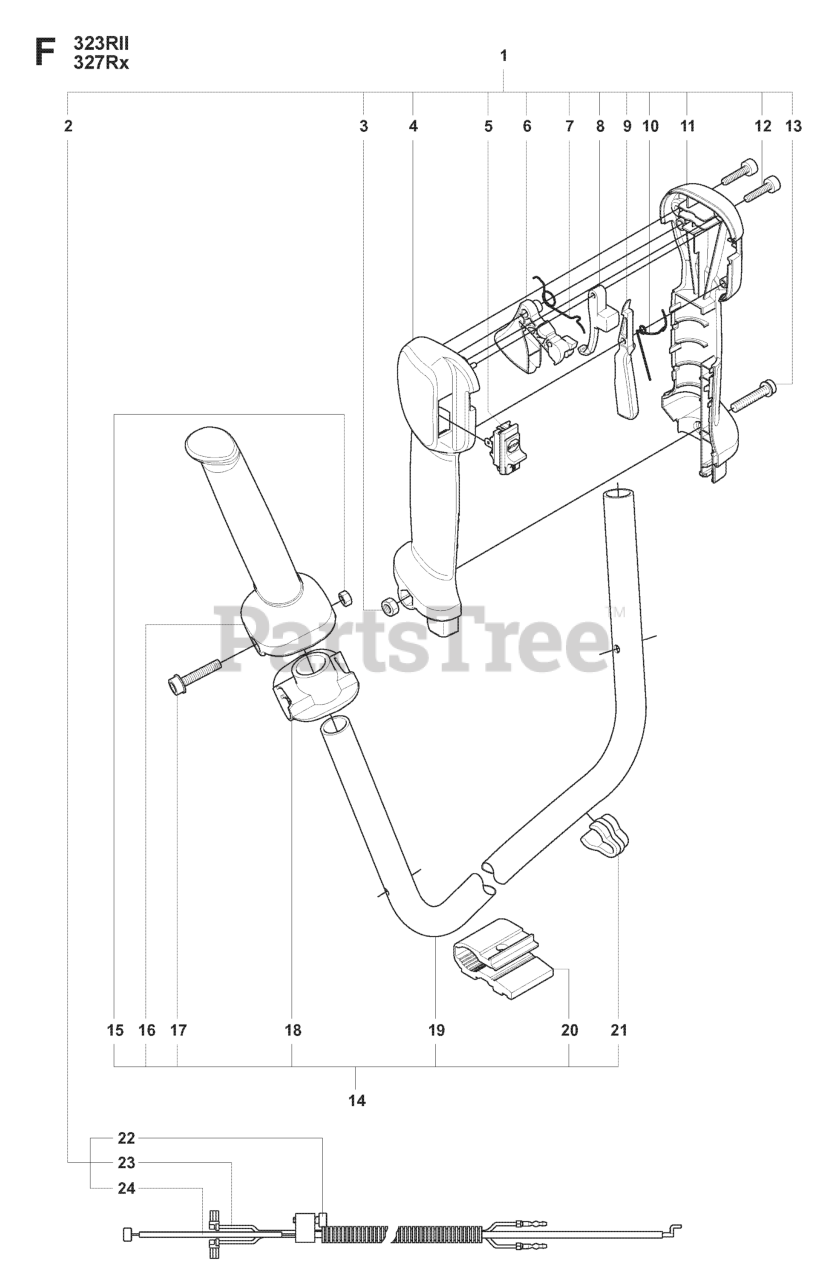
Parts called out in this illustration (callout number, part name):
1	HANDLE SYSTEM ASSY
4	HANDLE
5	STOP BUTTON
6	THROTTLE TRIGGER
8	LOCKOUT STARTER THROTTLE
9	THROTTLE LOCK
13	SCREW
24	THROTTLE WIRE
